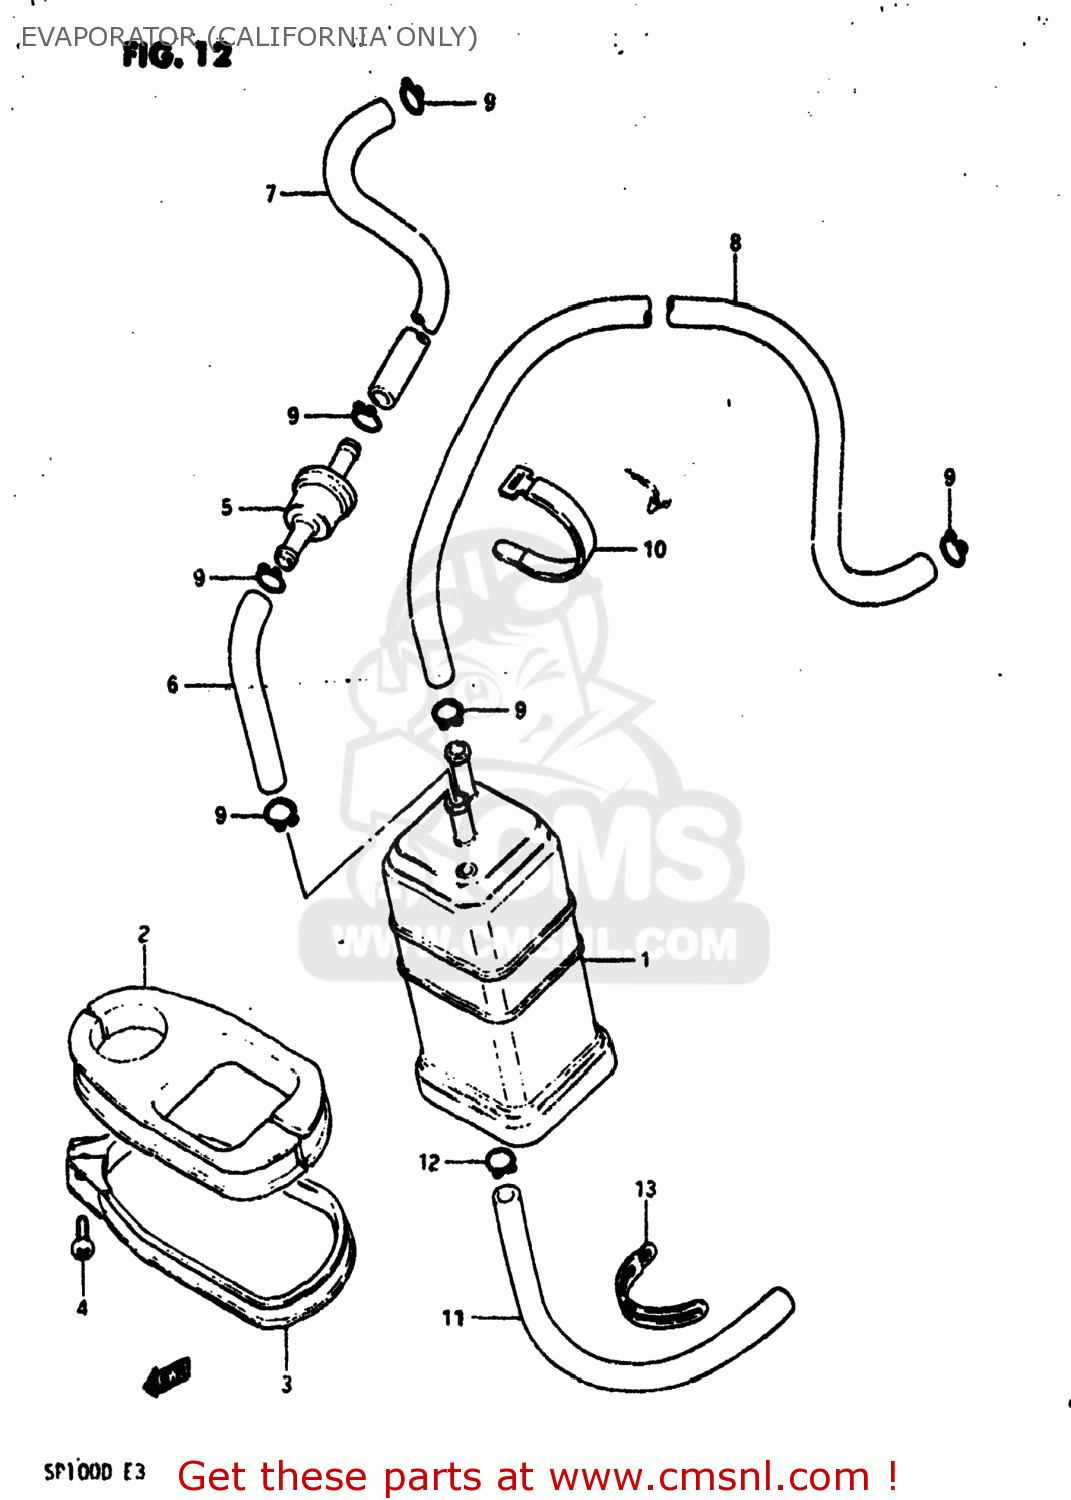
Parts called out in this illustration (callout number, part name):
1	CANISTER ASSEMBLY,CHARCOAL
2	CUSHION,CANISTER
4	SCREW
6	HOSE
7	HOSE
8	HOSE (L:510)
9	CLIP
10	CLAMP
11	HOSE
12	CLIP
13	CLAMP
